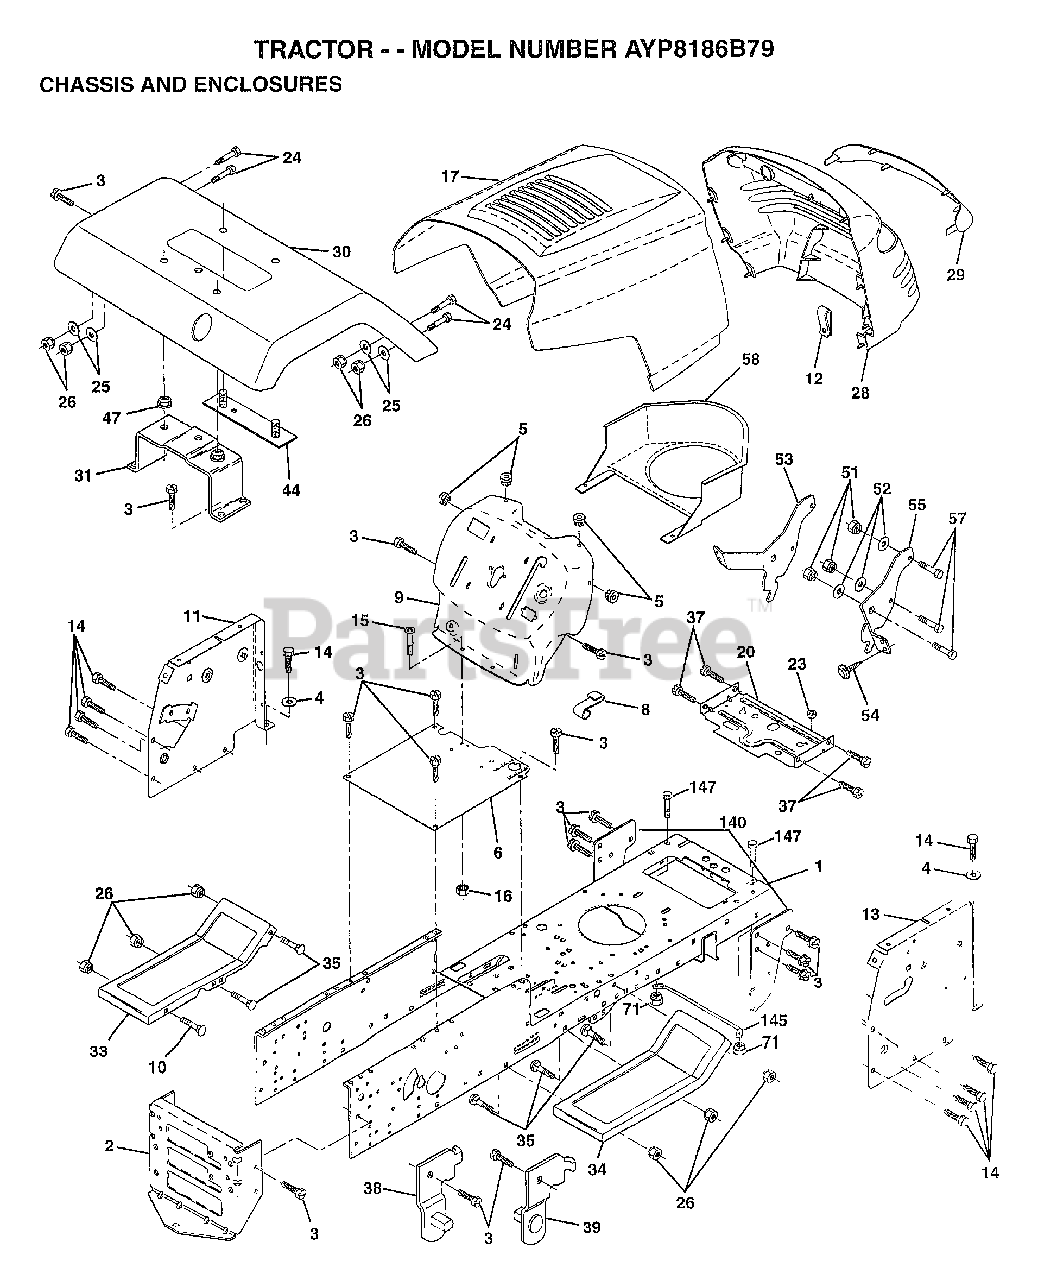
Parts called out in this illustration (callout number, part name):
1	CHASSIS ASM
3	SCREW
4	WASHER
5	BUMPER-HOOD/DASH
6	SADDLE
8	"CLIP,INSULATOR"
9	DASH SILKSCREEN
11	PANEL ASM DASH LH
12	CLIP.TINNERMAN
13	PANEL DASH RH
14	SCREW LT
15	SCREW
20	"PLATE-MTG,BATT/FU"
24	BOLT
25	WASHER
26	NUT
28	GRILLE-MS428
29	LENS GRILLE
30	FENDER.PNT.
31	BRKT.ASM.FENDER
33	FOOTREST.LH.LT/GT
34	FOOTREST.RH.LT/GT
35	BOLT
37	SCREW LT
37	BRACKET ASM RH
38	BRACKET ASM LH
44	STRAP ASM FENDER
47	NUT-PUSH YT
51	NUT
52	WASHER
53	BRACKET.GRILLE.LH
55	BRACKET.GRILLE.RH
58	DUCT.AIR.B&S.18HP
140	BRKT SUSPENSION
145	"ROD POVOT,CHASSIS"
147	BOLT LT
